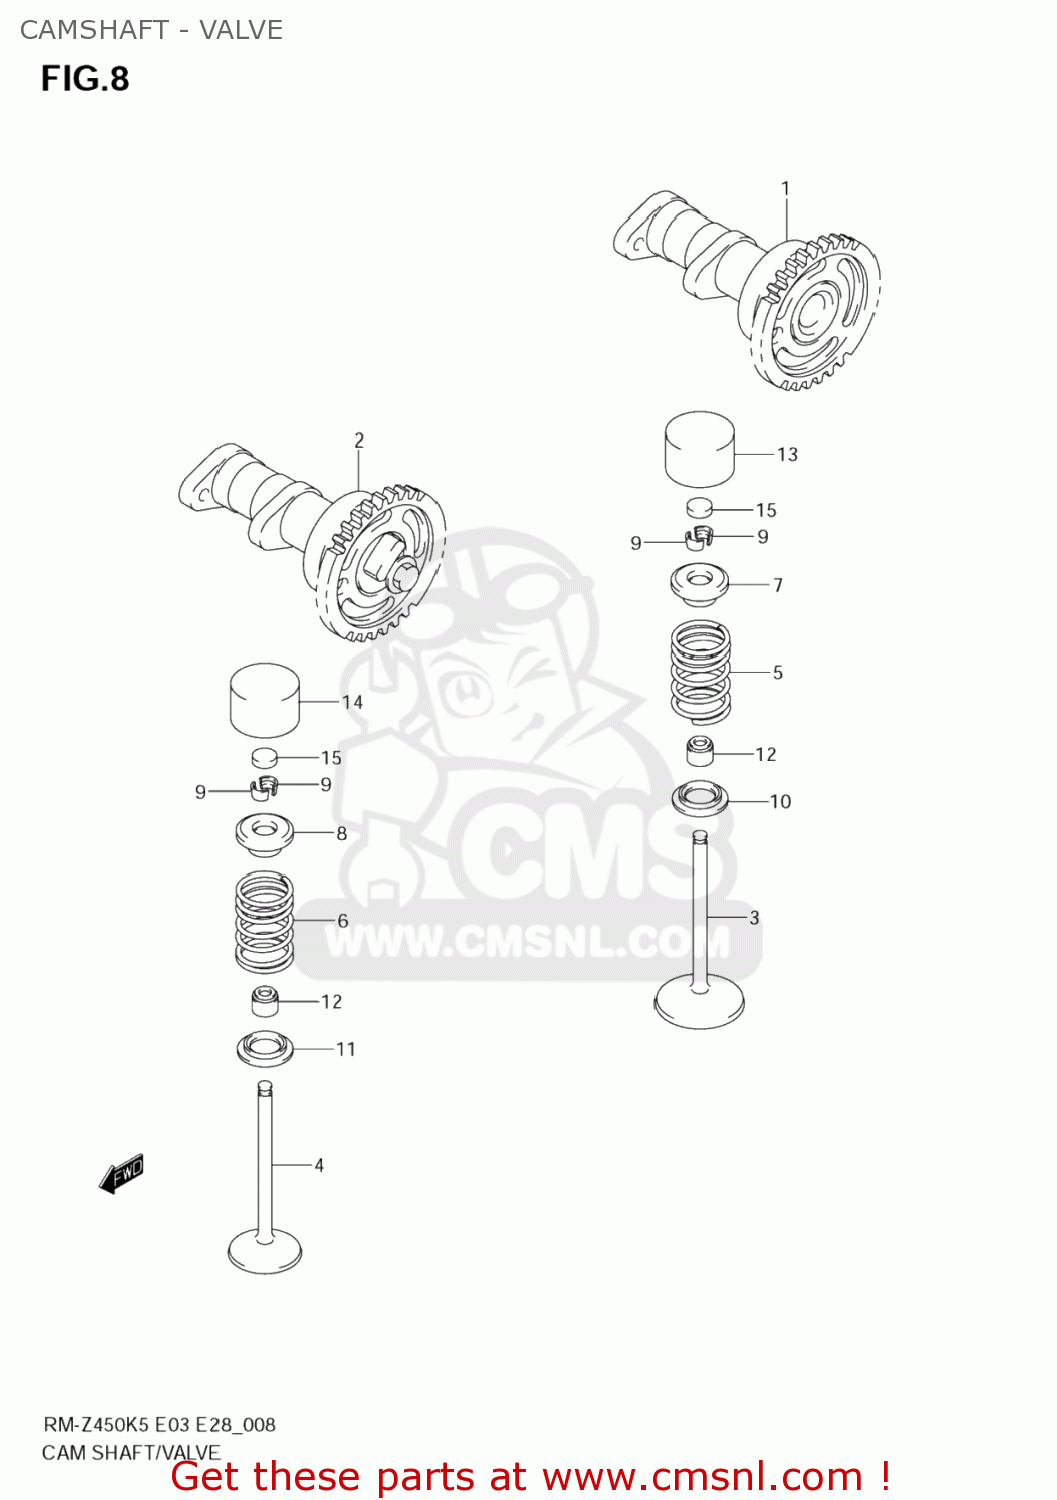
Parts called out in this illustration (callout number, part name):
1	CAMSHAFT,INTAKE
2	CAMSHAFT,EXHAUST
3	VALVE,INTAKE
4	VALVE,EXHAUST
5	SPRING,VALVE INTAKE
6	SPRING,VALVE EXHAUST
7	RETAINER,VALVE SPRING
8	RETAINER,VALVE SPRING EXHAUST
9	COTTER VALVE
10	SEAT,VALVE SPRING INTAKE
11	SEAT,VALVE SPRING EXHAUST
12	SEAL,OIL(5X10X9.7)
13	TAPPET
14	TAPPET
15	SHIM,TAPPET
16	SHIM SET,TAPPE
17	CASE,TAPPET SHIM
18	SHIM SET,TAPPET
19	CASE,TAPPET SHIM
20	SHIM SET,TAPPET
21	CASE,TAPPET SHIM
